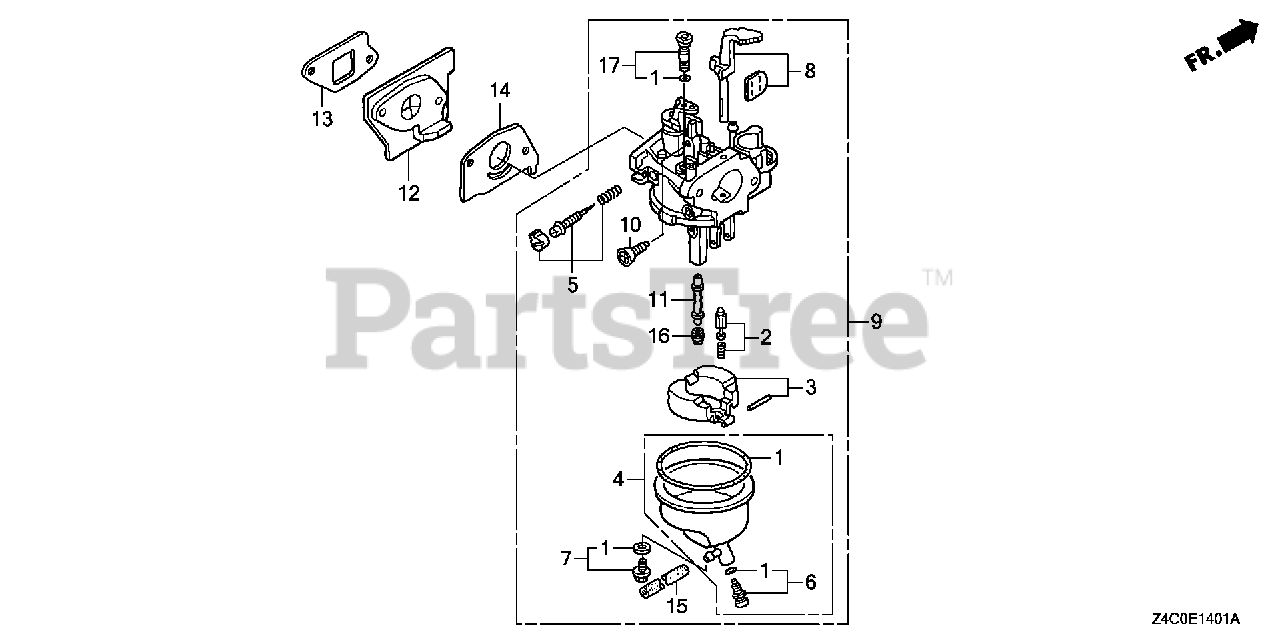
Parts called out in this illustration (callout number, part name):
1	GASKET SET
2	VALVE SET, FLOAT (SEAT NOT INCLUDED)
4	CHAMBER SET, FLOAT
5	SCREW SET, PILOT
6	SCREW SET, DRAIN
7	SCREW SET
8	CHOKE SET (CARBURETOR NO.)
9	CARBURETOR ASSY. (BF31H A/B)
9	CARBURETOR ASSY. (BF31M A)
10	SCREW, THROTTLE STOP
12	INSULATOR, CARBURETOR
13	GASKET, INSULATOR
14	GASKET, CARBURETOR
16	JET, MAIN (#48)
16	JET, MAIN (#50)
16	JET, MAIN (#52)
17	JET SET, PILOT (#35)
